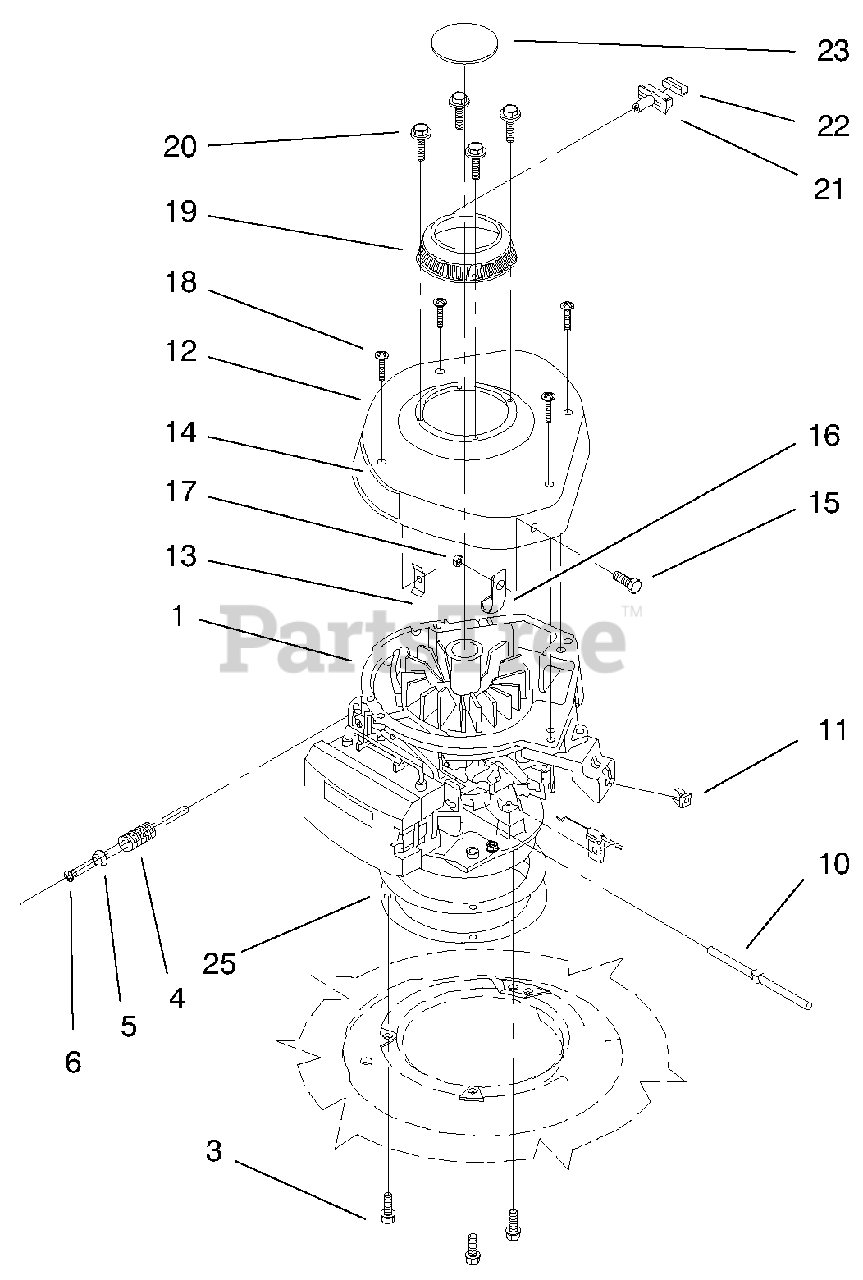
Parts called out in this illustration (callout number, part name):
1	Engine Assembly
3	Screw-Engine Mount
5	Actuator-Brake Lever
6	Retainer
10	Line-Gas
11	Nut-Speed
12	Shroud Assembly
13	Retainer-Applique
14	Applique
15	Screw-Hex Washer Hd.
17	Nut-Lock
18	Screw
19	Recoil Assembly
20	Screw-Sems
21	Handle-Starter
22	Clip-Rope Insert
23	Decal-Recoil
25	Plate-Engine
